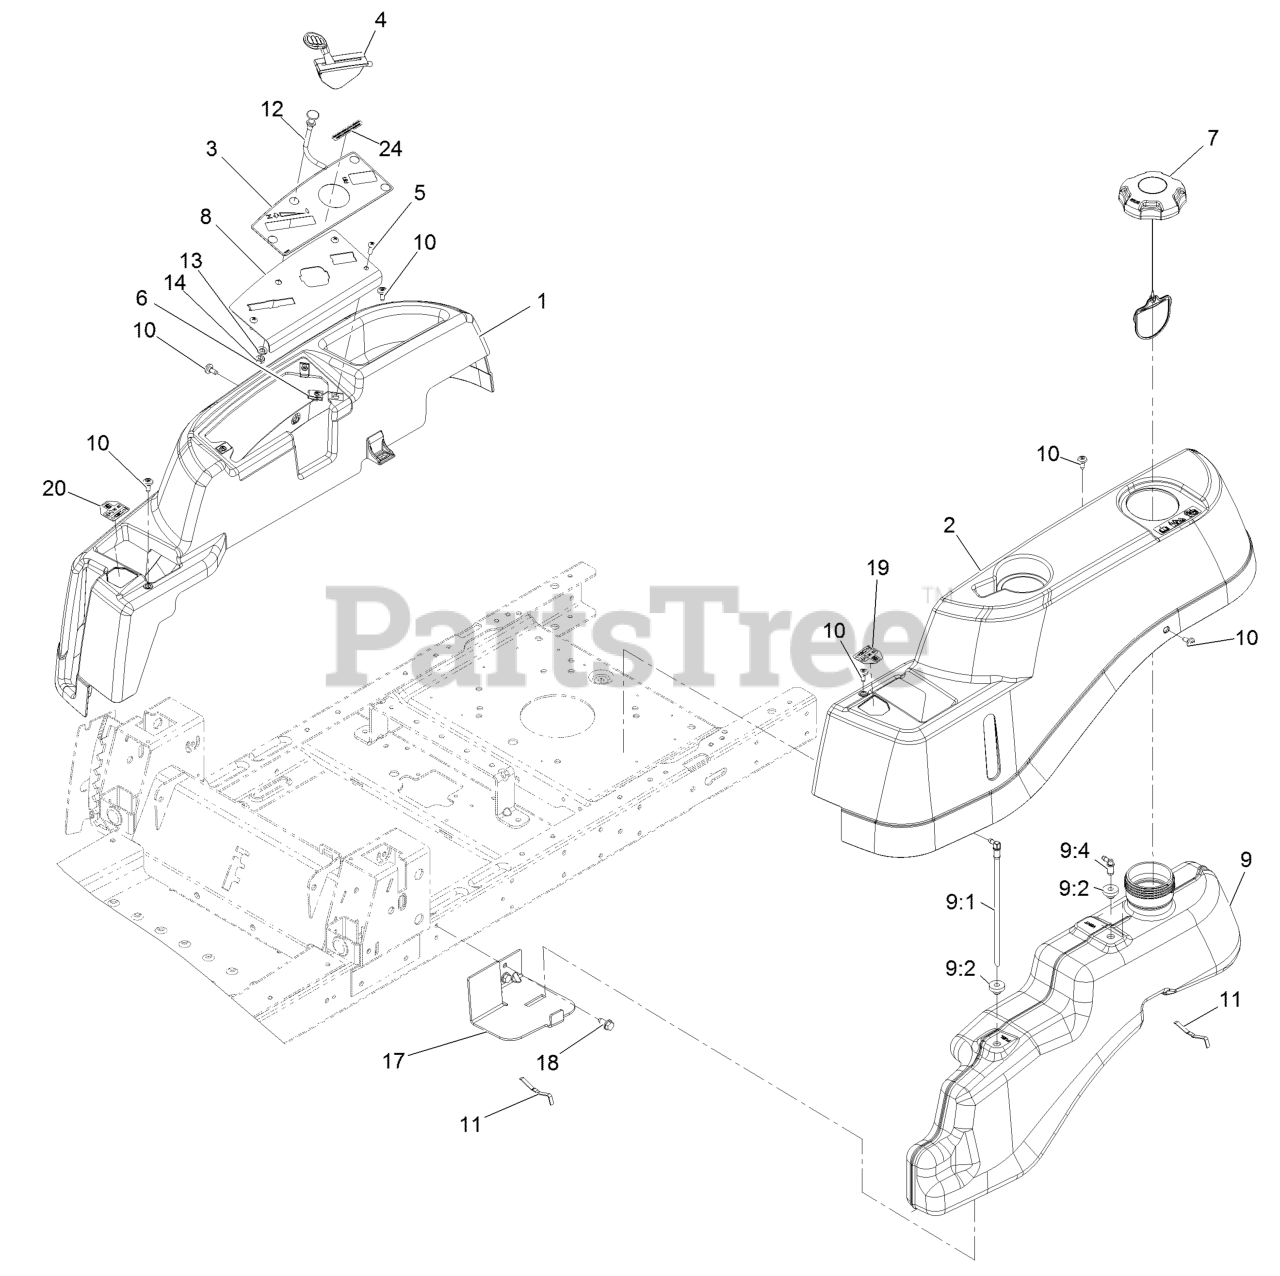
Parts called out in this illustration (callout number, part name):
3	DECAL-PANEL, CONTROL
4	CABLE-THROTTLE
5	SCREW-PRH
6	Nut-Retainer-Panel 1/4-20
8	PLATE-CONTROL
9	FUEL TANK ASM
9:1	CONNECTOR-ELBOW, 90 DEG
9:2	BUSHING
9:4	FITTING-PLASTIC
10	SCREW-SHOULDER
11	SPRING
12	CABLE-CHOKE
13	WASHER-LOCK
14	NUT-HJ
17	SUPPORT-TANK, FRONT
18	Screw-HWH 5/16-18 X 3/4 Tf
19	DECAL-LEVER, CONTROL (LH)
20	DECAL-LEVER, CONTROL (RH)
24	DECAL-SHUTDOWN
